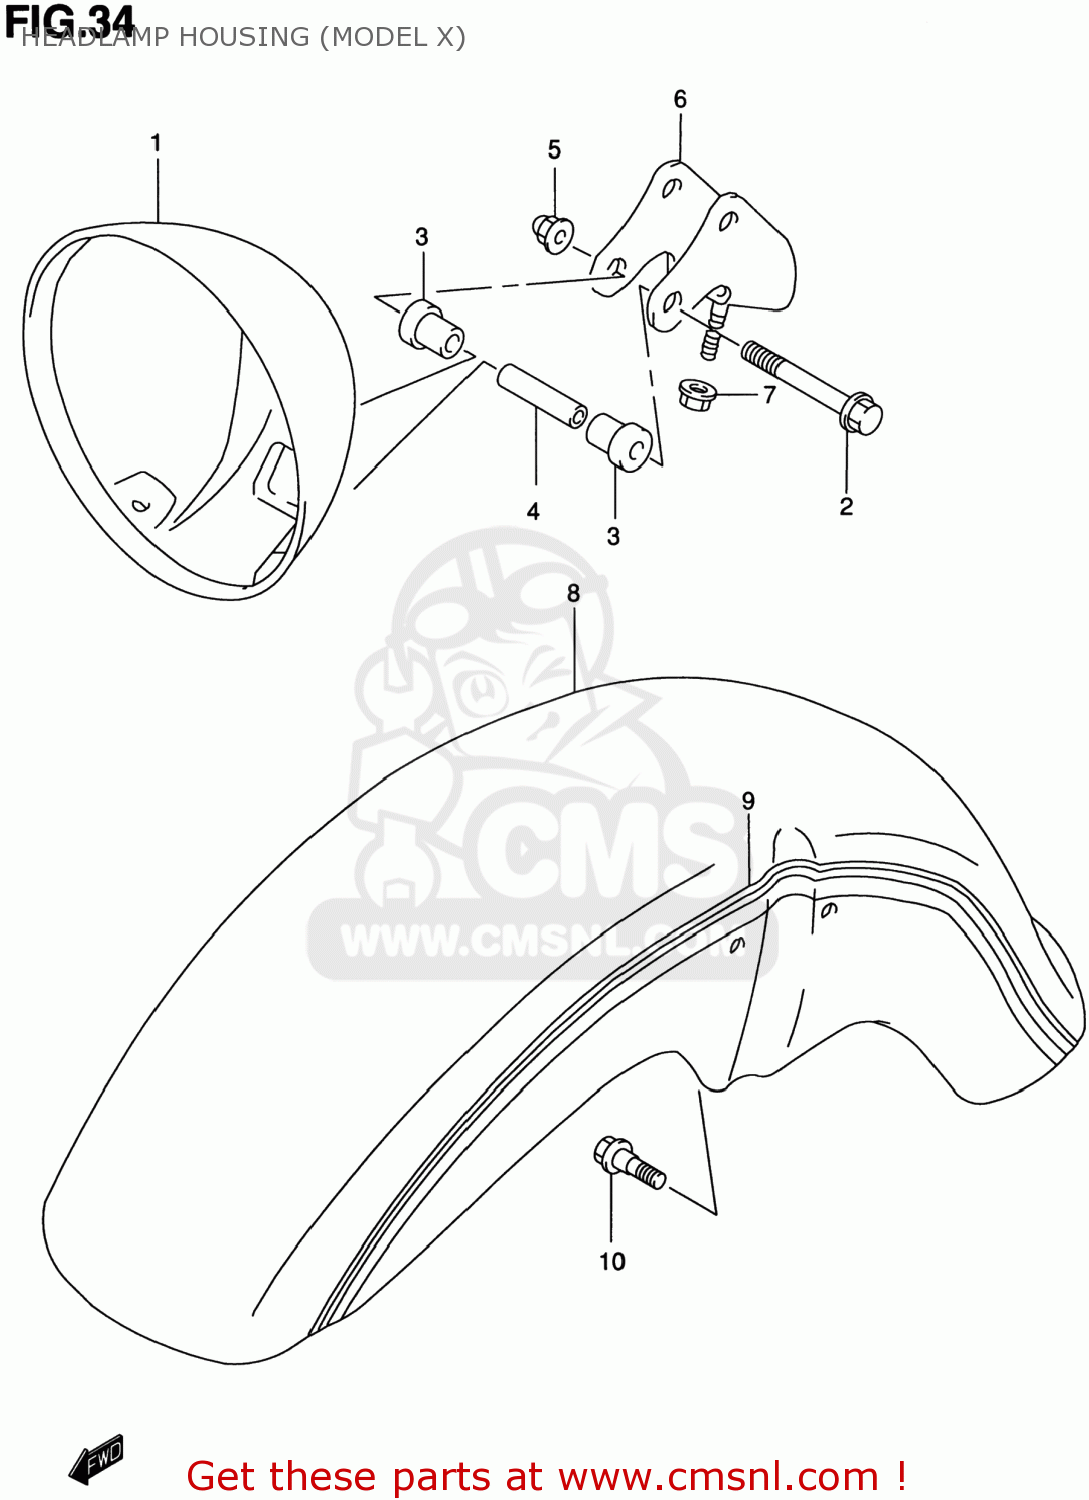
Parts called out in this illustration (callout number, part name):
1	HOUSING,HEADLAMP
2	BOLT
3	CUSHION,HEADLAMP HOUSING
4	SPACER(6.5X9X38.3)
5	NUT
6	BRACKET COMP,HEADLAMP
7	NUT
8	FENDER SET,FRONT (GREEN)
9	TAPE SET,FR FENDER
10	BOLT(6X16)
